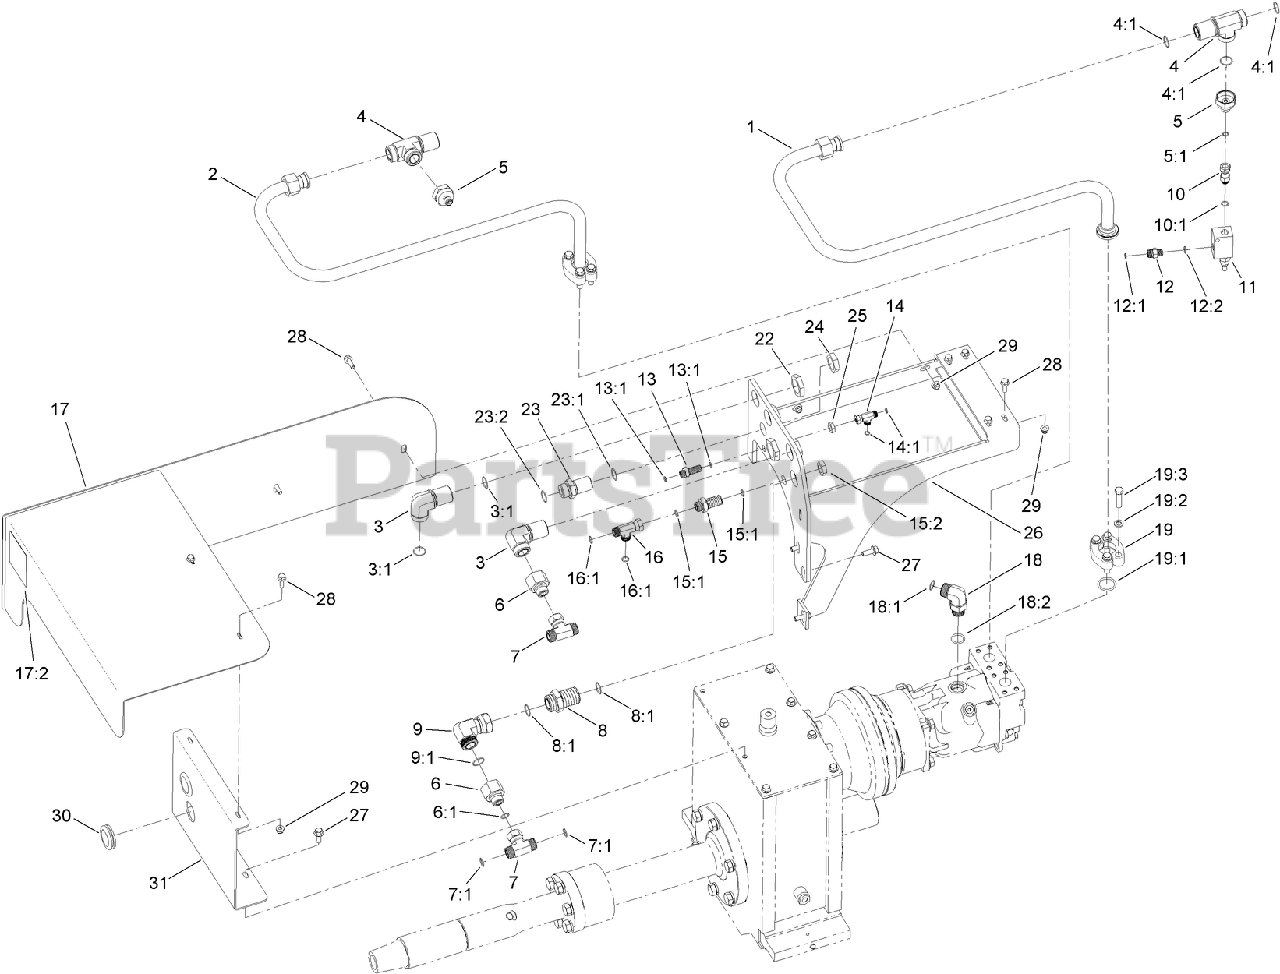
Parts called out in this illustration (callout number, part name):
1	TUBE-HYD, ROTARY B (BULKHEAD TO MOTOR)
2	TUBE-HYD, ROTARY A (BULKHEAD TO MOTOR)
3	FITTING-ELBOW, 90
3:1	O-RING
4	FITTING-TEE, BULKHEAD
4:1	O-RING
5	FITTING-REDUCER
5:1	O-RING
6	FITTING-REDUCER
6:1	O-RING
7	FITTING-HYD, TEE
7:1	O-RING
8	ADAPTER-HYD
8:1	O-RING
9	FITTING-SWIVEL, 90 DEG
9:1	O-RING
10	CONNECTOR-SWIVEL, STRAIGHT
10:1	O-RING
11	VALVE-RELIEF, PRESSURE
12	FITTING-STRAIGHT
12:1	O-RING
12:2	O-RING
13	UNION-BULKHEAD
13:1	O-RING
14	FITTING-HYD
14:1	O-Ring
15	FITTING-BULKHEAD
15:1	O-RING
15:2	NUT-BULKHEAD
16	FITTING-HYD, TEE
16:1	O-RING
17	CARRIAGE GUARD ASM
17:2	DECAL-WARNING, CRUSHING
18	FITTING-ELBOW-90
18:1	O-RING
18:2	O-RING
19	HYD FLANGE KIT
19:1	O-RING
19:2	WASHER-LOCK
19:3	SCREW-HH
22	NUT-BULKHEAD
23	FITTING-STRAIGHT
23:1	O-RING
23:2	O-RING
24	NUT-BULKHEAD
25	NUT-LOCK
26	MOUNT-HOSE CARRIER, ROTARY
27	SCREW-HHF
28	SCREW-HHF
29	NUT-LOCK, HHF
30	Grommet
31	PLATE-SUPPORT, GUARD
